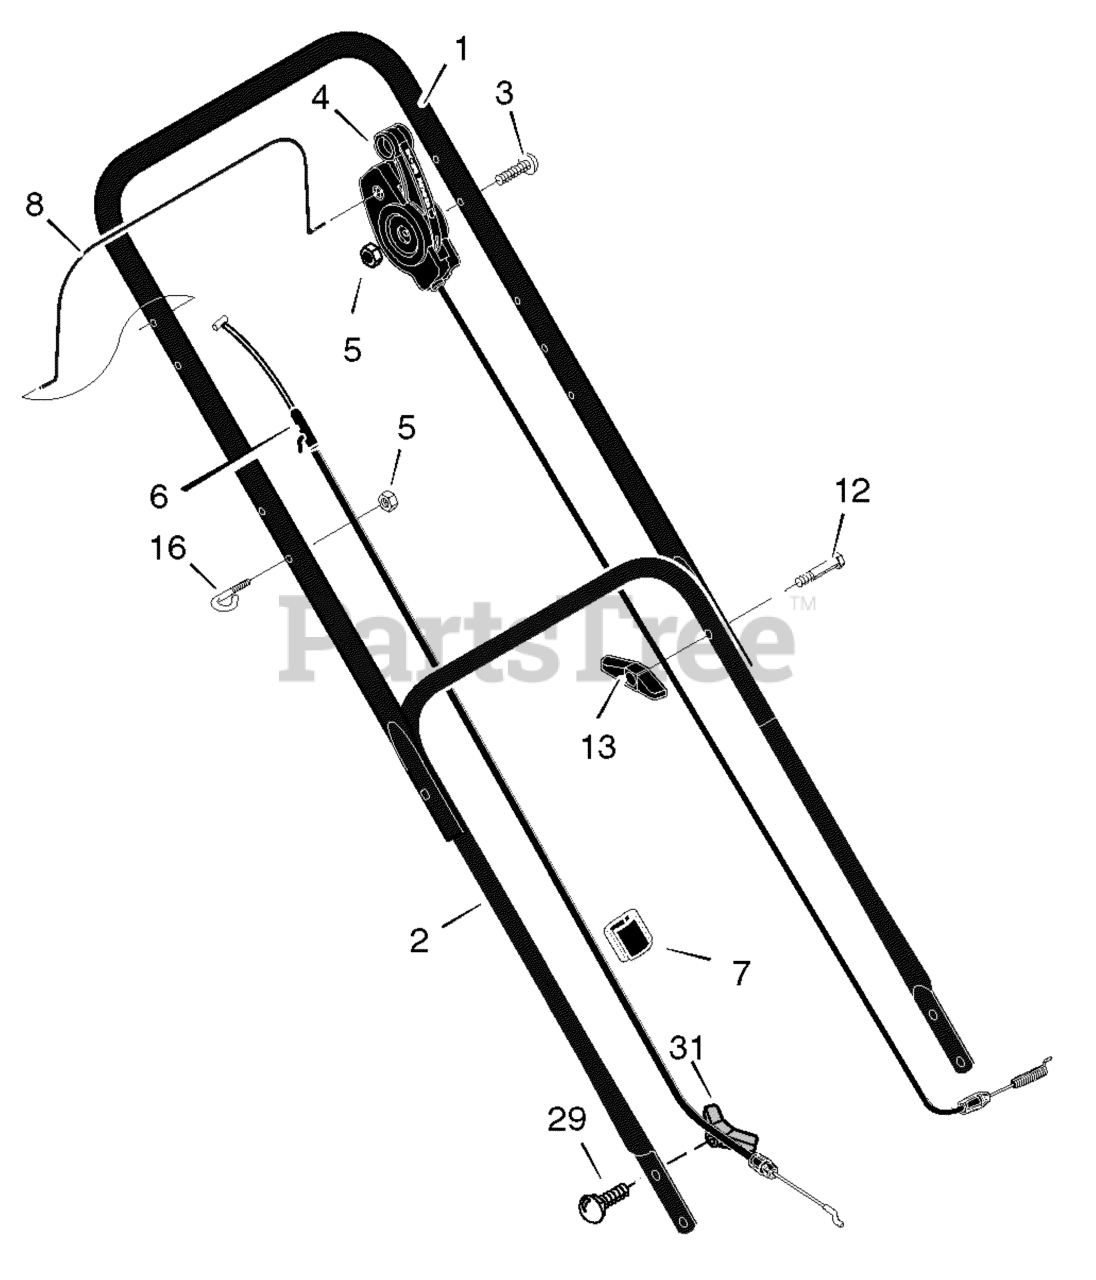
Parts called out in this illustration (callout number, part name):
1	Handle, Upper (Black)
1	Handle, Upper (Gray)
2	Handle, Lower (Black)
2	Handle, Lower (Gray)
4	Control, Drive
5	Locknut
6	Cable, Stop (Briggs)
6	Cable, Stop, (Tecumseh)
7	Fastener, Double Cable
8	Lever, Stop
16	Guide, Rope
29	Bolt, Carriage
31	Knob, Plastic
